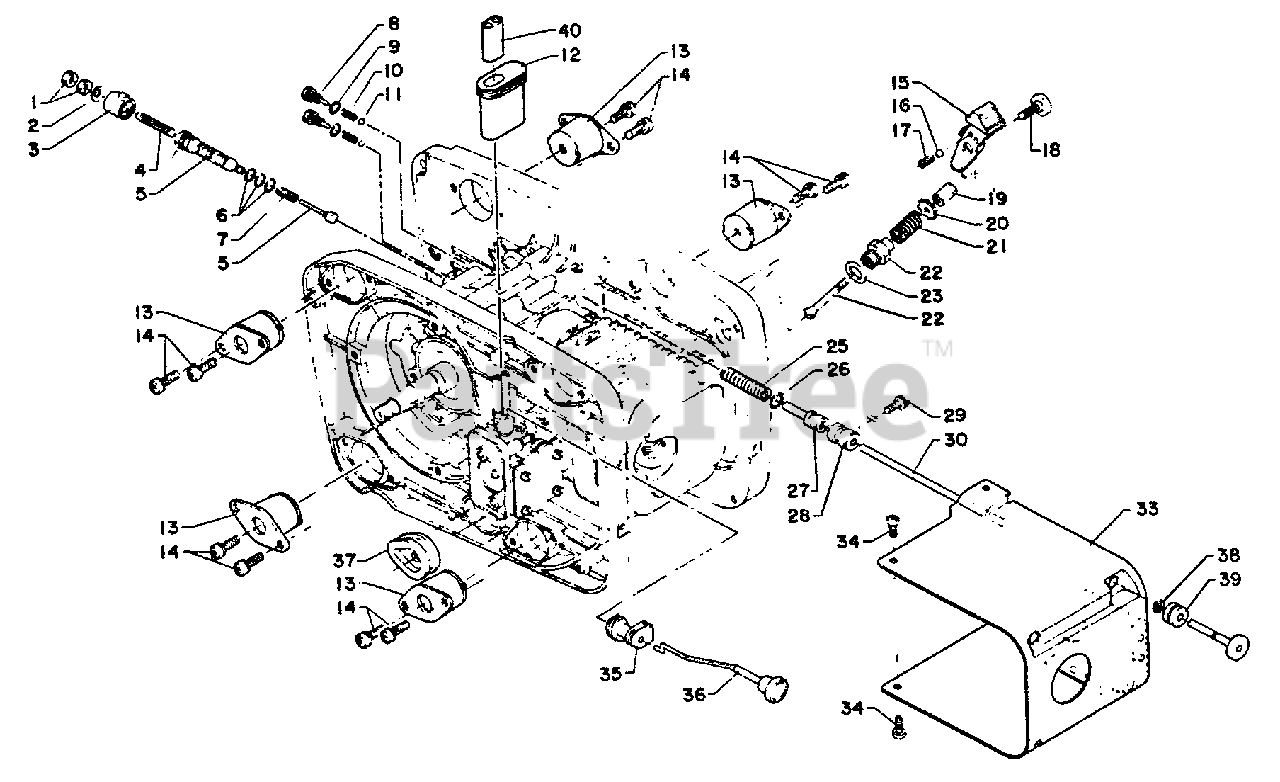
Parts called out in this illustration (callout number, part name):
1	NUT M5
2	LOCKWASHER
3	DIAL, AUTO-OILER
4	SCREW, ADJUST
5	PUMP KIT
8	ADAPTER, OIL PUMP
10	SPRING, VALVE
11	VALVE, BALL
13	CUSHION, RUBBER
14	SCREW 5×12
15	LEVER, PRESSURE RELEASE
16	VALVE, BALL
18	SCREW, SET
19	NUT
22	DECOMPRESSION ASSY
23	VALVE SEAT PACKING
25	PUMP SPRING
26	O-RING 6 MM
27	PISTON, OIL PUMP
28	PUMP PISTON COVER
29	SCREW 4×12
30	PUMP ROD
33	COVER, ENGINE
34	SCREW - 4×10
35	GROMMET
36	ROD, CHOKE
37	GROMMET
38	E-RING 3
39	GROMMET
40	GUIDE
